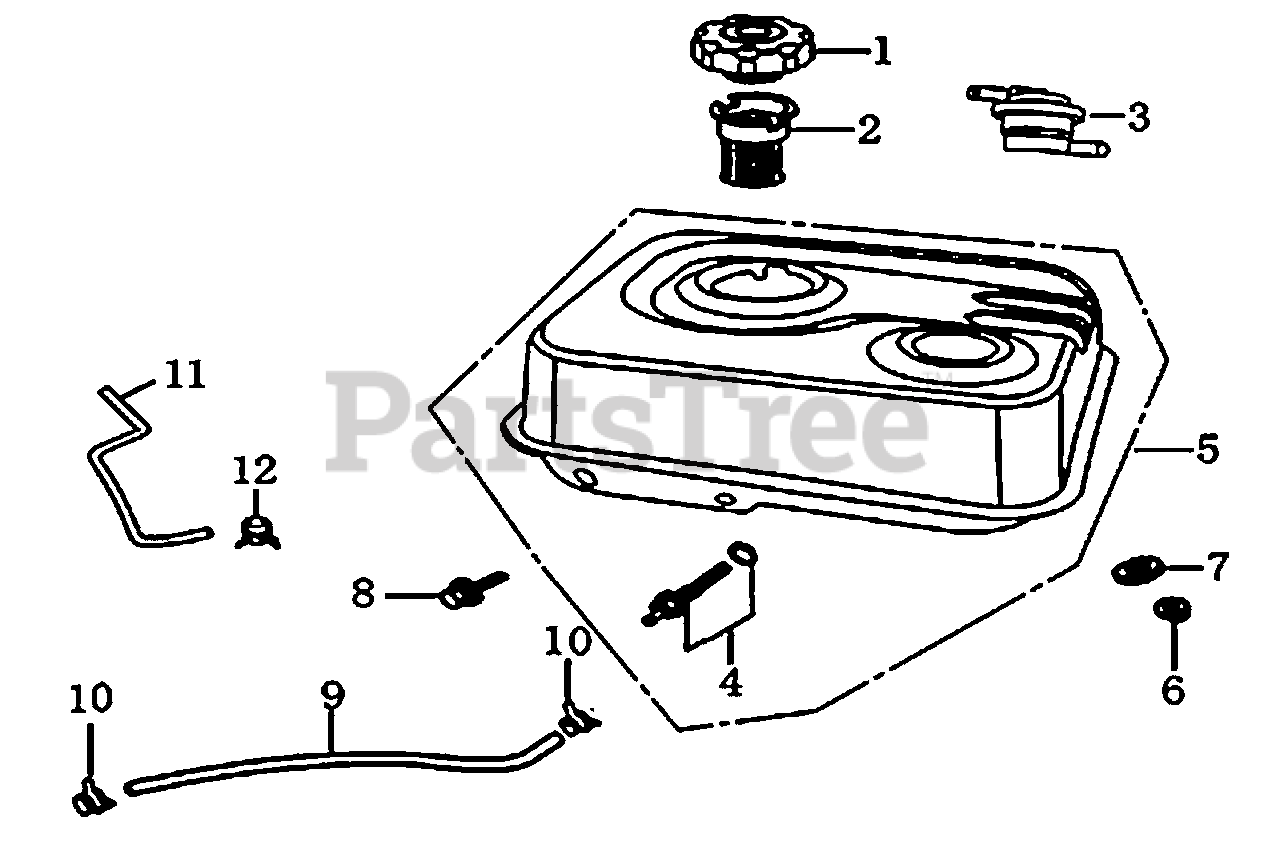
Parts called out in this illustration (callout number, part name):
1	CAP, FUEL FILLER
2	FILTER, FUEL
3	GAS VALVE, FUEL TANK
4	JOINT ASSY., FUEL TANK
5	TANK COMP., FUEL
6	NUT, FLANGE
7	WASHER, RUBBER
8	BOLT, FLANGE
9	HOSE, FUEL
10	CLAMP, HOSE
11	HOSE, FORMED
12	CLAMP, HOSE
